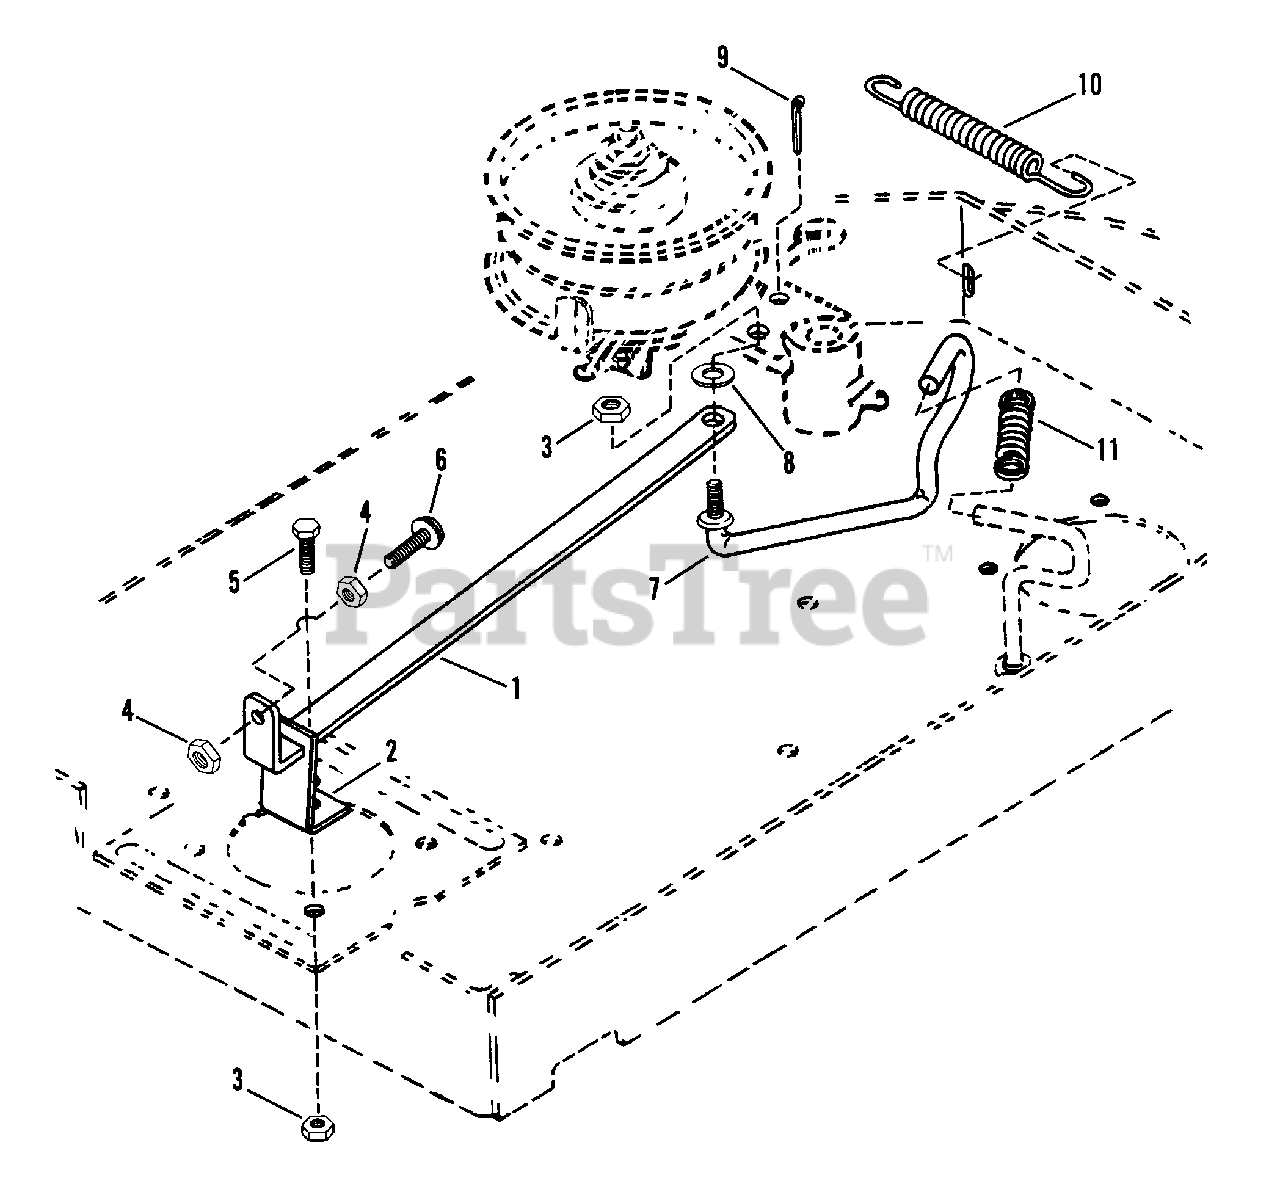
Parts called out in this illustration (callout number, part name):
1	ARM, Brake, 36" Deck
2	BRACKET, Brake Arm
3	NUT, 3/8-16 HEX NYLON LOCK
4	NUT, 5/16-18 Hex Jam
5	SCREW, 3/8-16 x 1 1/2" Hex Head Cap
6	BOLT, 5/16-18 x 1 1/4" Carriage, Grade 2
7	GUIDE, Brake Belt
8	WASHER, 3/8 Wave
9	COTTER-PIN, 3/16 x 3/4"
10	SPRING, Idler Return
11	SPRING, Traction
